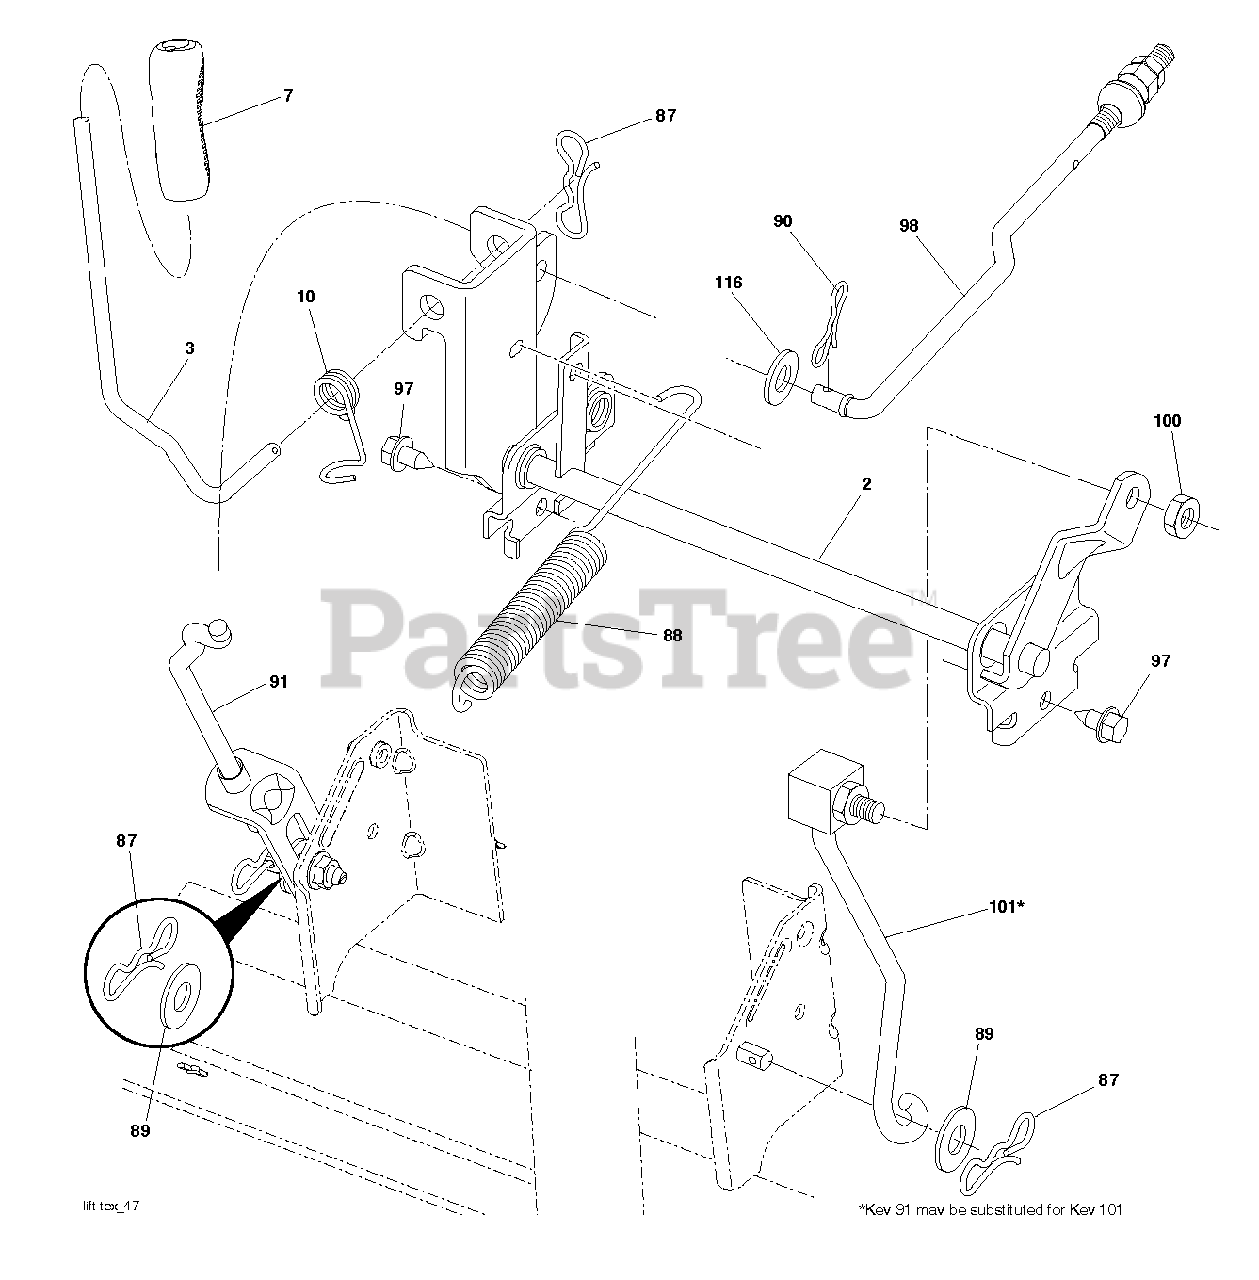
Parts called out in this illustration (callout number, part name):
2	SHAFT.ASM.CROSS.LIFT
3	LEVER.LIFT.HANDLE.LT
7	GRIP.HANDLE.LIFT.PVC.BLACK
10	SPRING.TORSION.LIFT.HANDLE
87	PIN.COTTER.7/16.BOW TI.
88	SPRING.LIFT.ASSIST
89	WASHER.CLEAR.ZINC
90	PIN.COTTER.5/16.BOW TI
91	LINK.ASM.LIFT.REAR
97	SCREW, 3/8-16X3/4
98	LINK.ASM.SUSP.FRONT.MW
100	LOCKNUT
101	LINK.ASM.LIFT.FIXE.38/42/46"
